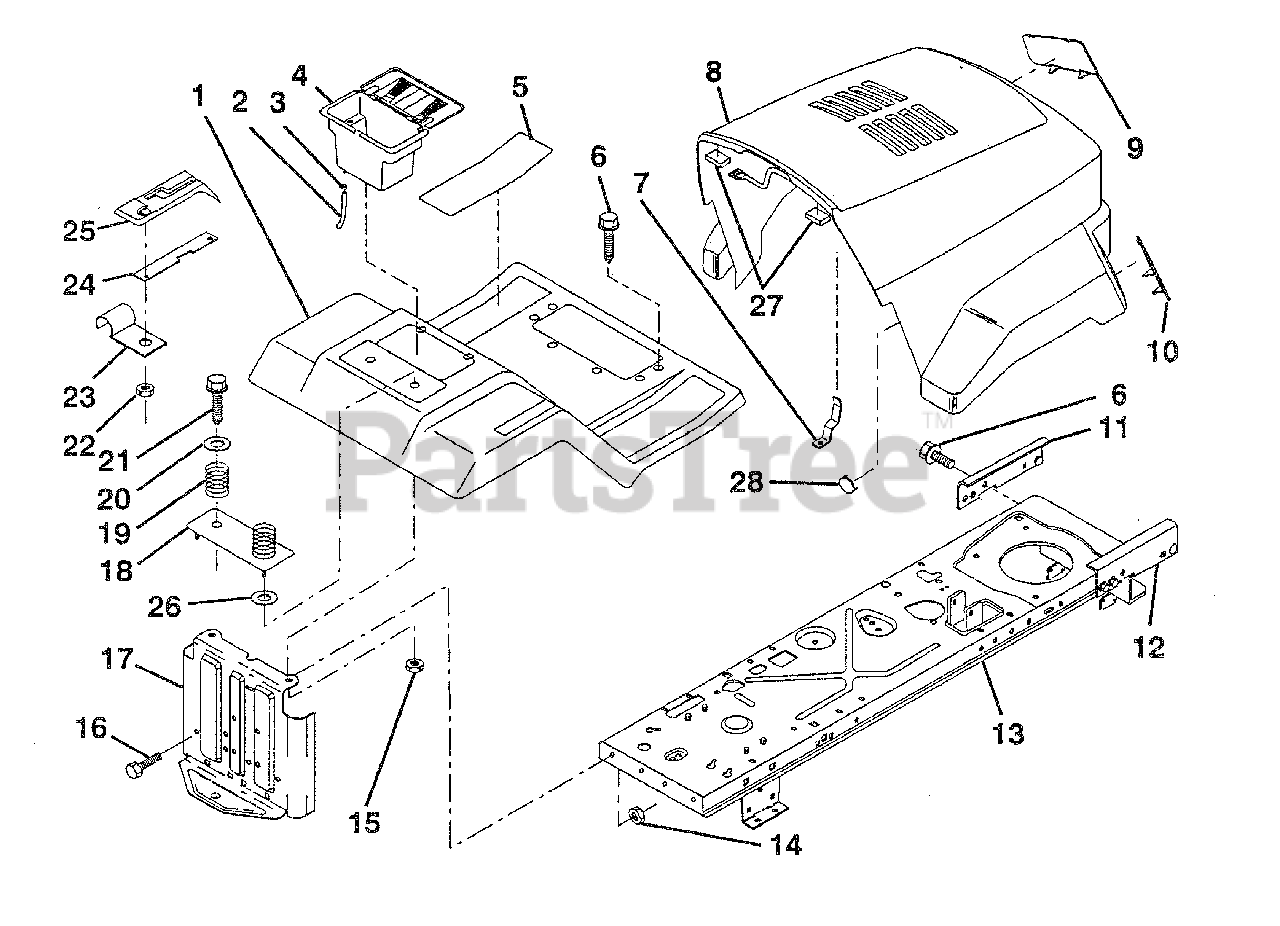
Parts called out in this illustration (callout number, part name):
1	Fender/Footrest
2	Tube, Battery Drain
3	Clamp, Hose
4	Case, Battery
5	Pad, Footrest
6	Screw, Hex Wsh. Thrdrol. 5/16-18 x 3/4
7	Latch, Hood
8	Hood/Grill Asm.
9	Lens, L.H.
11	Bracket, Asm. Pivot Frame, L.H.
12	Bracket, Asm. Pivot Frame, R.H.
13	Assembly, Frame
14	Nut, Crownlock 5/16-18
15	Nut, Keps 1/4-20 UNC
16	Bolt, Hex Hd. 5/16-18 UNC x 3/4
18	Plate, Asm. Battery
19	Spring, Compression, Seat
20	Washer 13/32 x 1-1/4 x 12 Ga.
21	Screw, Hex Wsh. Thrdrol. 3/8-16 x 3/4
22	Nut, Self-Threading, Washer Head 3/16
23	Clip, Insulated
24	Bar, Shift Lock
25	Console, Shift Control
26	Washer 9/32 x 7/8 x 13 Ga.
27	Bumper, Hood
28	Plug Socket Light
